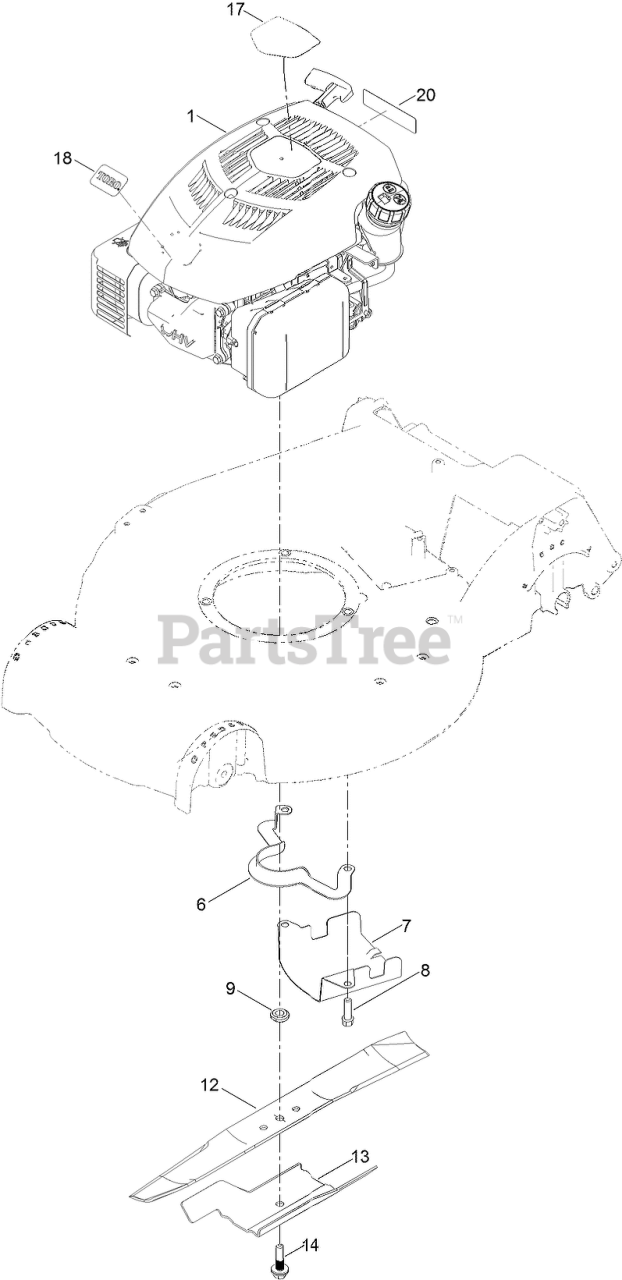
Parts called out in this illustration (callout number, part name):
1	ENGINE-1P65F-2
6	GUIDE-BELT
7	SHIELD-GRASS
8	SCREW-TAPTITE
9	Spacer-Driver
12	BLADE-21IN, RECYCLING
13	Accelerator-Blade
14	BOLT-BLADE
17	DECAL-SHROUD
20	DECAL-ARRESTER, SPARK
